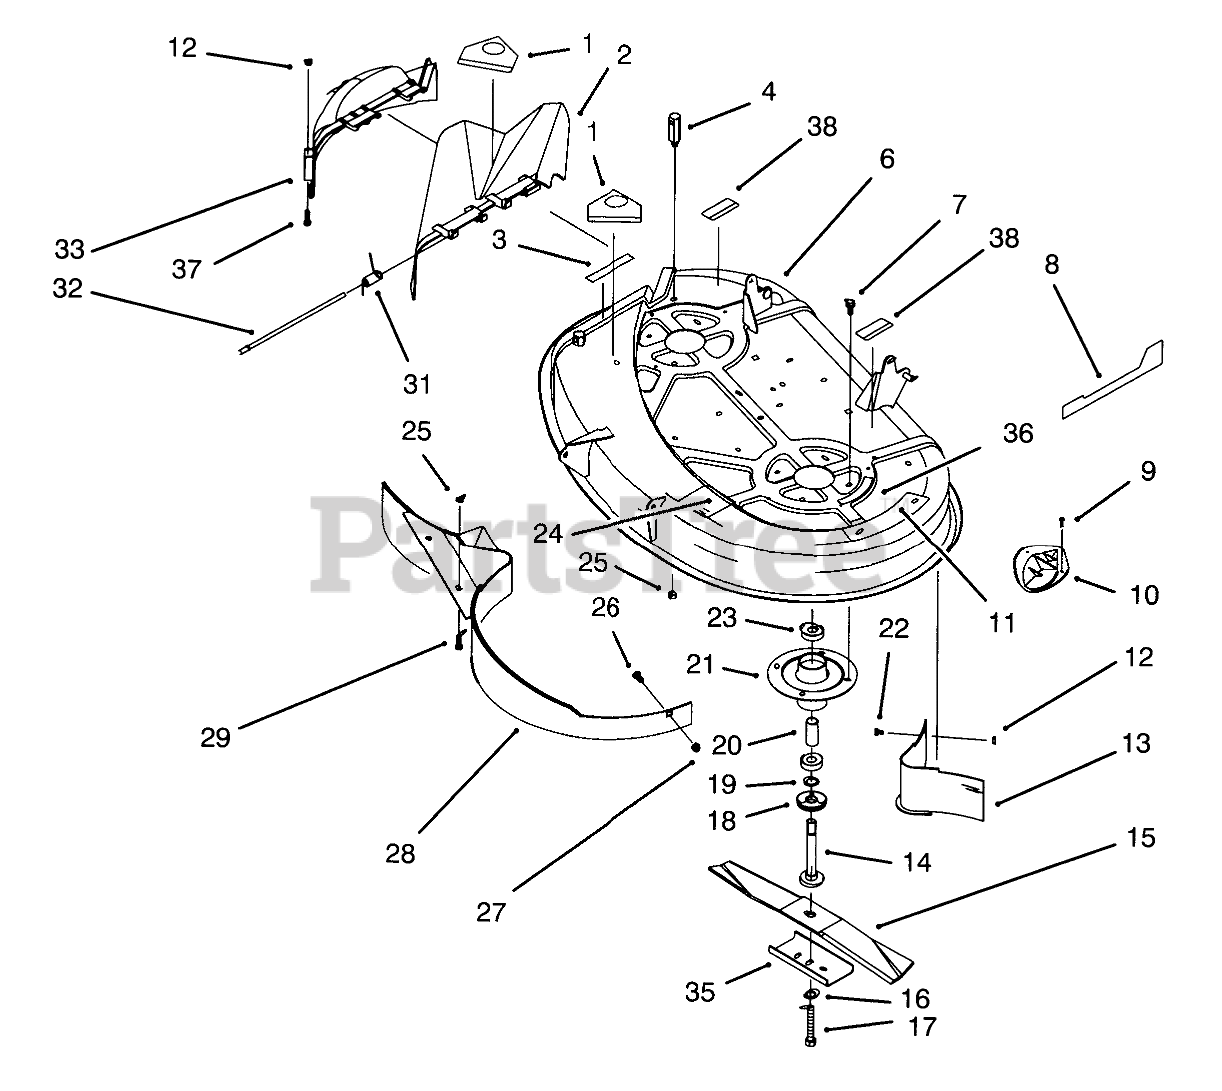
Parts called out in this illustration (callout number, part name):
1	DECAL-DANGER
2	Deflector-Deck
3	DECAL-DANGER, DEFLECTOR
4	REAR PIVOT POST (PLTD)
6	Deck-38"
7	SCREW-TAPTITE
8	DECAL-38" RECYCLER
9	SCREW-PPH
10	PLATE-KICKER
11	DECAL-DANGER
12	NUT-LOCK, NI
13	Baffle-Rear
14	SHAFT-SPINDLE
15	Blade
16	WASHER-BELLEVILLE
17	SCREW-HH
18	SHIELD-BEARING
19	SPACER
20	SPACER
21	HOUSING-SPINDLE
22	SCREW-HH
23	BEARING-BALL
24	Decal-Routing
25	NUT-LOCK, NI
26	BOLT-CARR
27	NUT-LOCK, NI
28	Baffle-38"
29	SCREW-HH
31	SPRING
32	ROD-HINGE DEFLECTOR
33	COVER-RECYCLER
35	Stiffener
36	DECAL-DANGER, SHIELD
37	SCREW-HH
38	DECAL-WARNING
